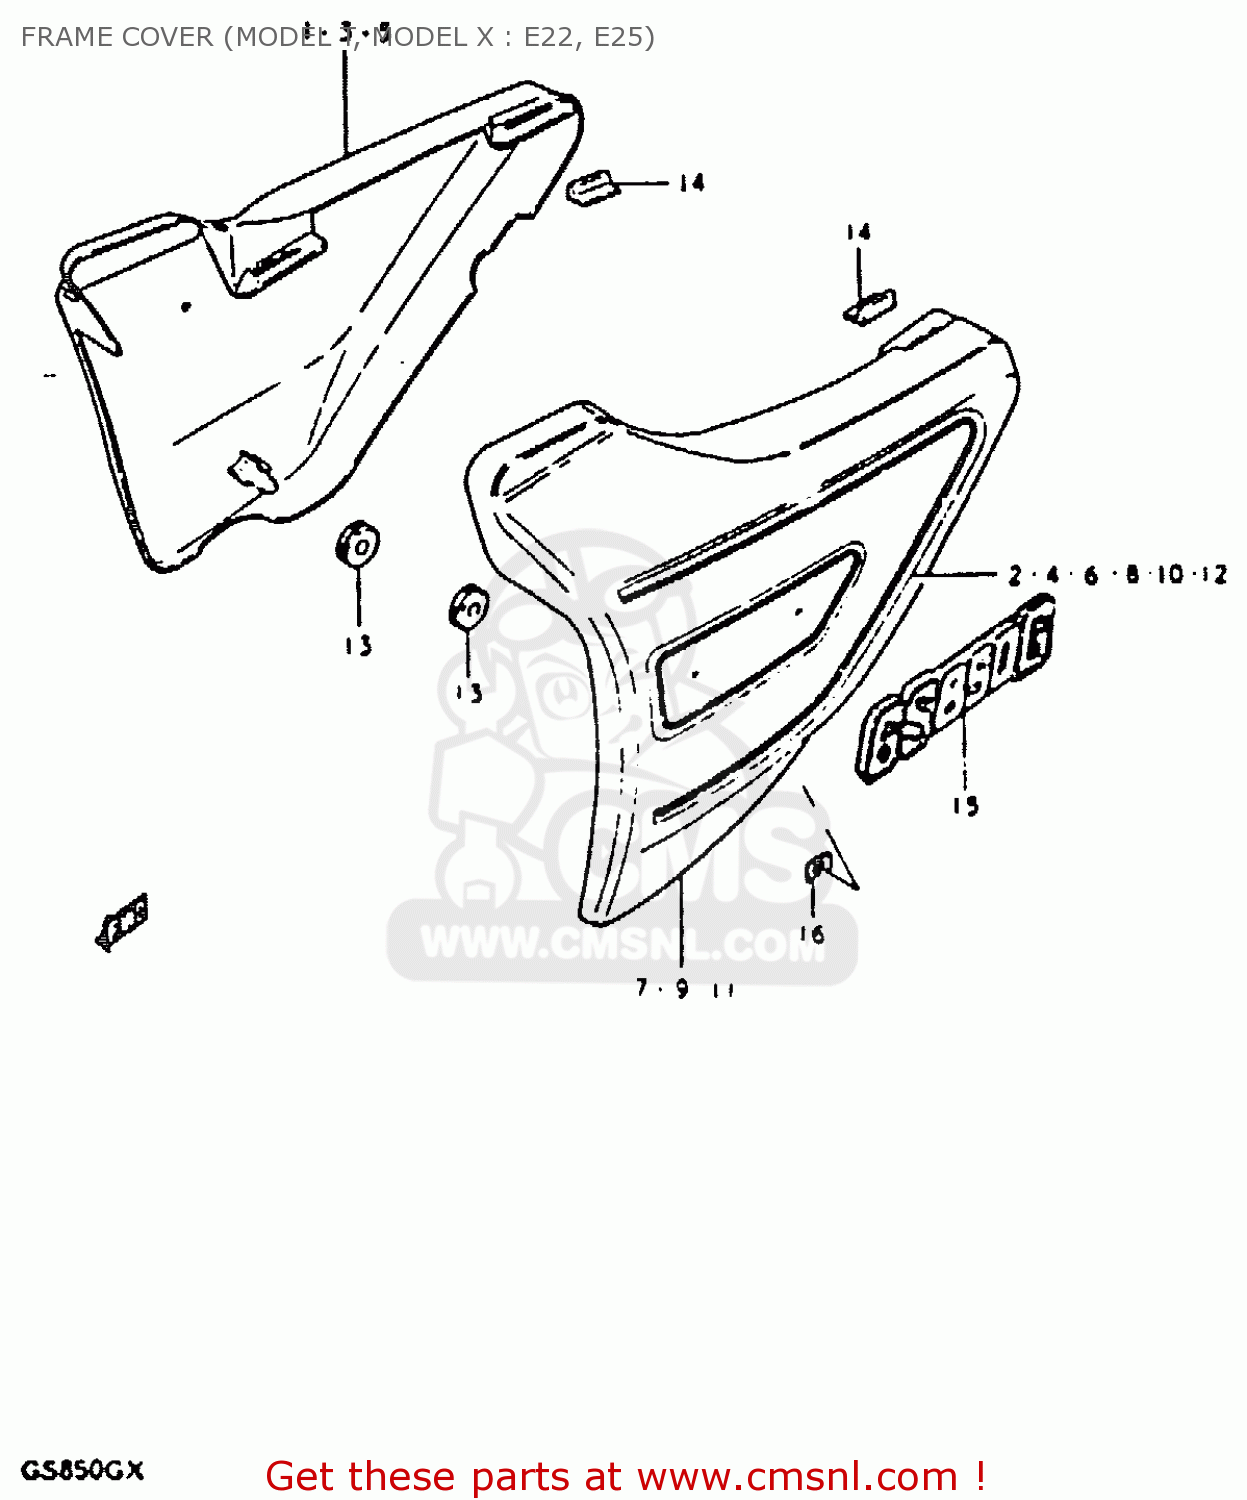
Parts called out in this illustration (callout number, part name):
1	COVER, FRAME RH (BLACK)
2	TAPE, RH
3	COVER, FRAME RH (SILVER)
4	TAPE, RH
5	COVER, FRAME RH (MAROON)
6	TAPE, RH
7	COVER, FRAME LH (BLACK)
8	TAPE, LH
9	COVER, FRAME LH (SILVER)
10	TAPE, LH
11	COVER, FRAME LH (MAROON)
12	TAPE, LH
13	CUSHION
14	CUSHION,FRAME COVER
15	EMBLEM,FRAME COVER
16	NUT
